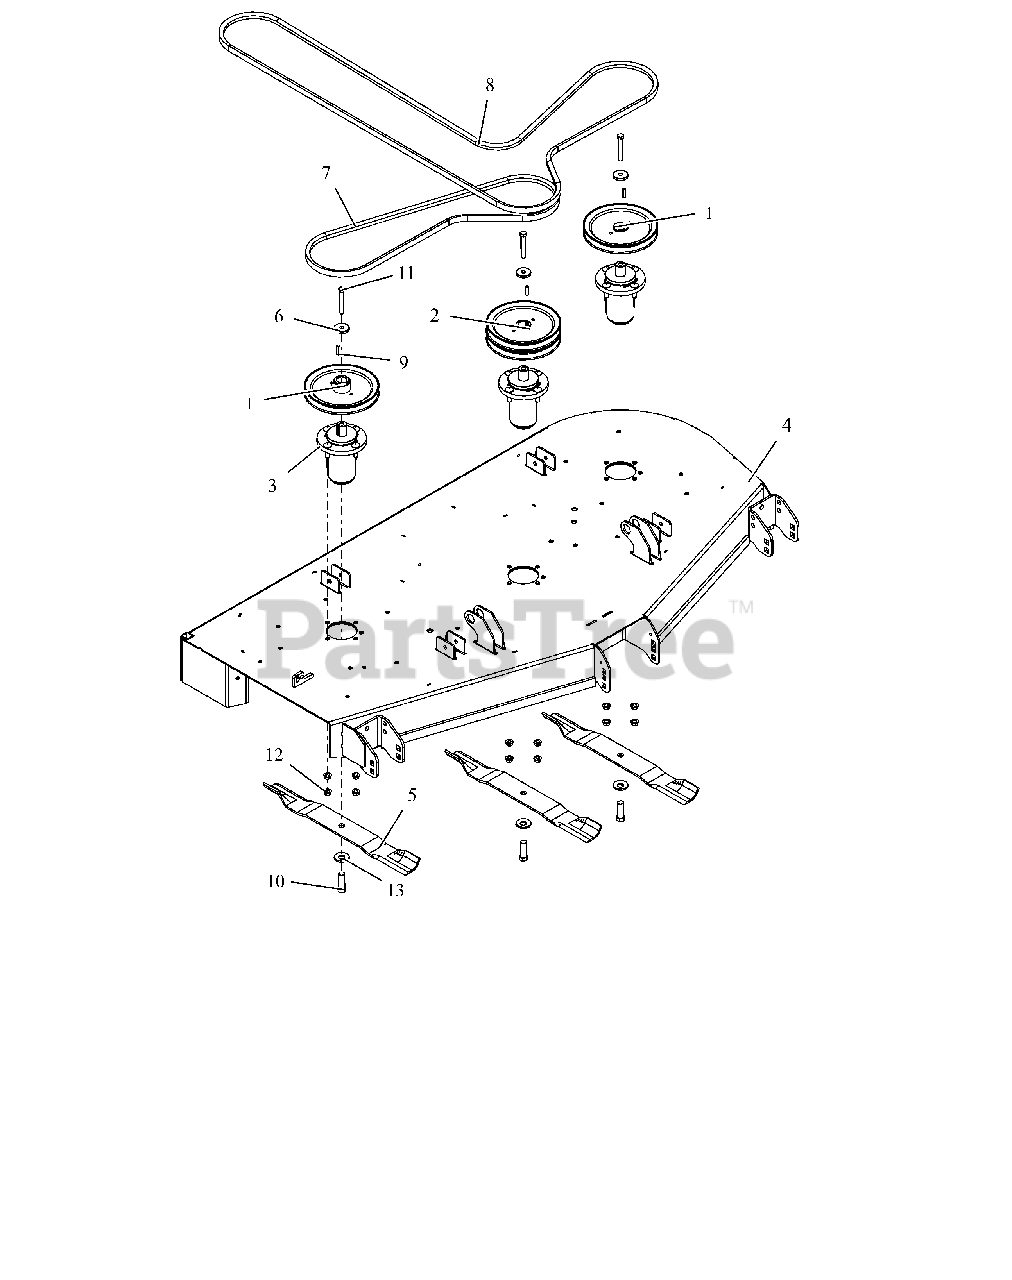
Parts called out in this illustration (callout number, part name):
1	PULLEY, V-7.50 OD X 1"ID
2	PULLEY, DOUBLE 1"X7.50"&7.50" (BLACK)
3	ASM, MAINT FREE ALUM SPINDLE
4	KIT,DECK-60" W/DECALS-GRAVELY
5	BLADE, 20.5"
6	RETAINER, SHEAVE
7	V-BELT, B-COGGED
8	V-BELT, HB SECTION
9	KEY, SQ .25X.25X1.00 RC 40-50
10	BLT, HEX .62-18X1.75 G8 ZCC
11	BLT, HEX .38-16X2.75 G8 ZCC
12	NUT-LK-CTR-FLG .375-16 GF ZCC
13	WSHR-BLVL .669X1.535X.138
